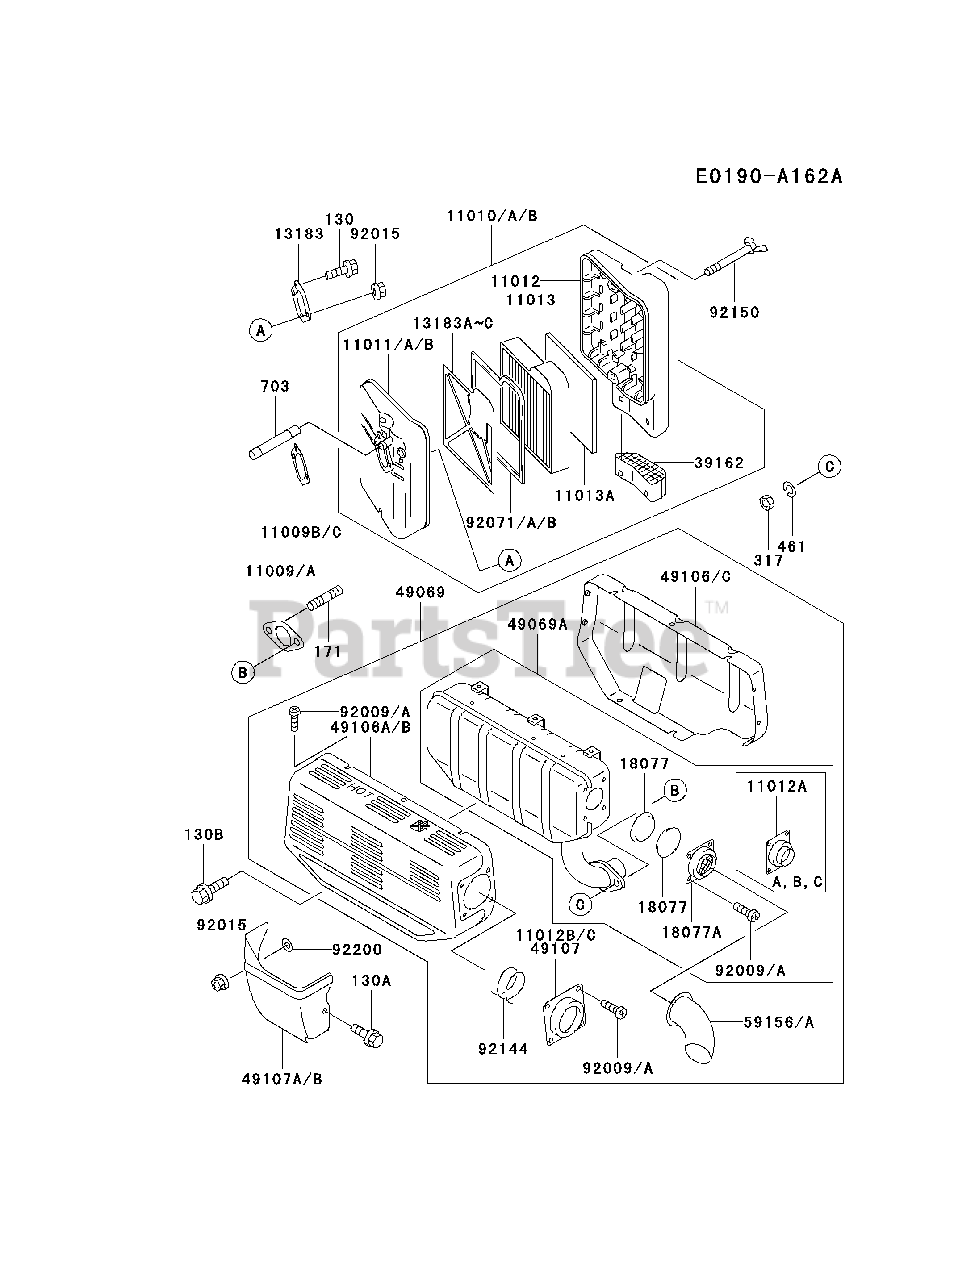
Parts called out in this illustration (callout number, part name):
130	BOLT-FLANGED
130A	BOLT-FLANGED
130B	BOLT-FLANGED
171	BOLT-STUD
317	NUT-HEX-SMALL
461	WASHER-SPRING
703	TUBE-RUBBER
92200	WASHER
